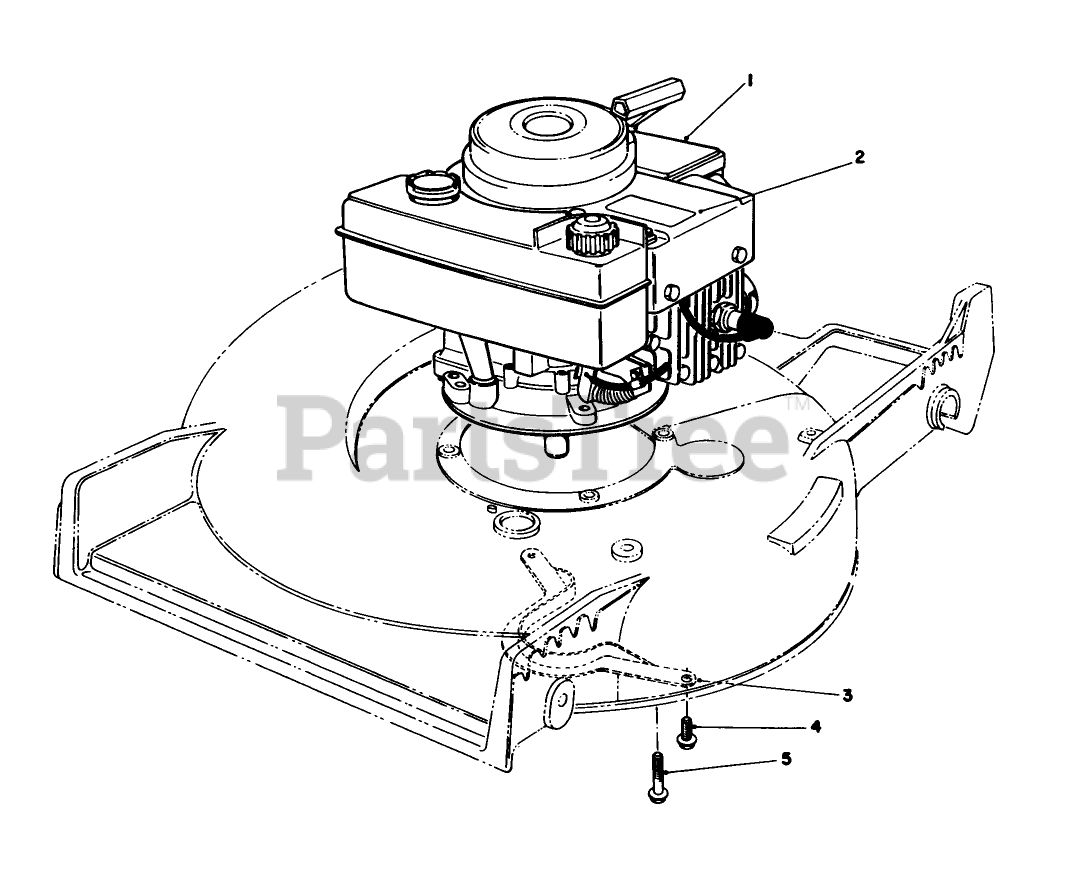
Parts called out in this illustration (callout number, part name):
2	Decal-Engine
3	BBC BELT GUIDE
4	SCREW-HWHTF
5	3/8-16 X 2 CAPSCREW
